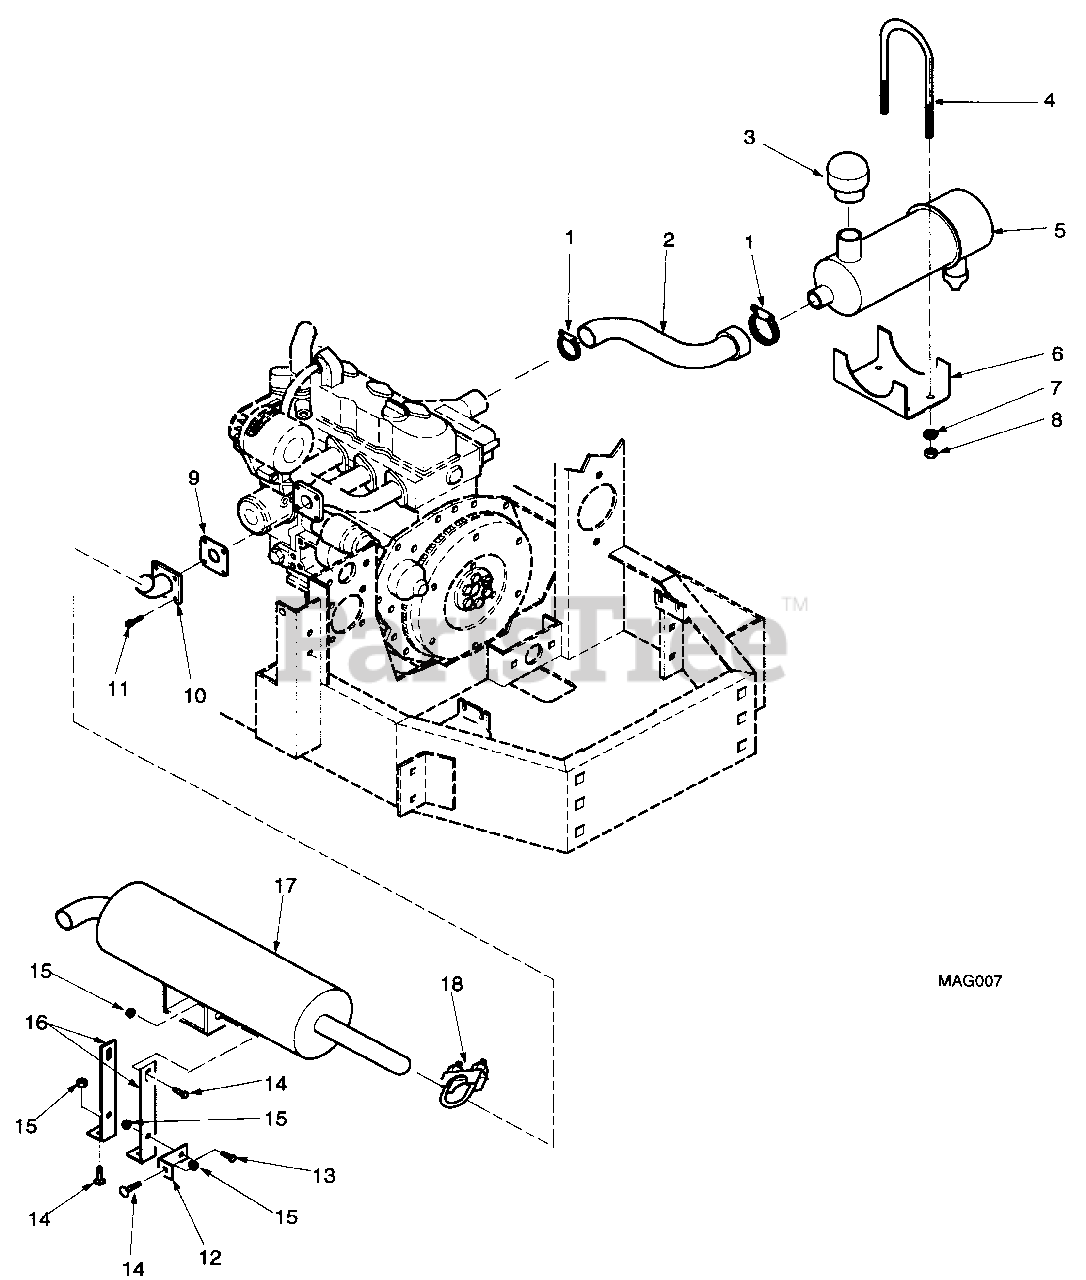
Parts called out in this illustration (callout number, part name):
1	HOSE CLAMP
2	HOSE, AIR INTAKE
3	CAP. PRECLEANER
4	U-BOLT
5	AIR CLEANER
6	MOUNTING BRACKET, AIR CLEANER
7	LOCKWASHER, 5/16
8	NUT, HEX, 5/16-18
9	GASKET, MANIFOLD
10	ADAPTER, MANIFOLD
11	CAPSCREW, SOCKET HEAD, M8-1.125 X 20
12	BRACE, MUFFLER SUPPORT
13	BOLT, HEX HEAD, 5/16-18 X 1
14	CARRIAGE BOLT, 5/16-18 X 3/4
15	SERR. FL. HEX NUT, 5/16-18
16	BRACKET, MUFFLER SUPPORT
17	MUFFLER
18	CLAMP, EXHAUST PIPE
